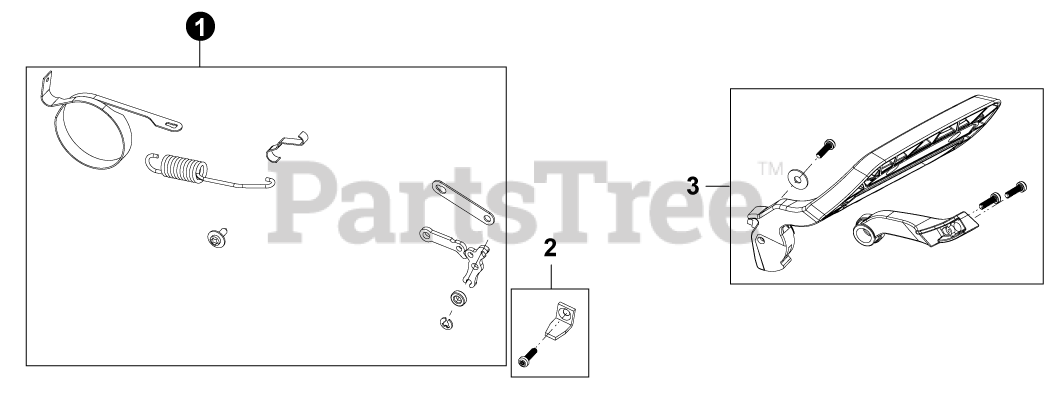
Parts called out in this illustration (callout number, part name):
1	KIT, CHAIN BRAKE
2	CATCHER, CHAIN
3	LEVER, CHAIN BRAKE
